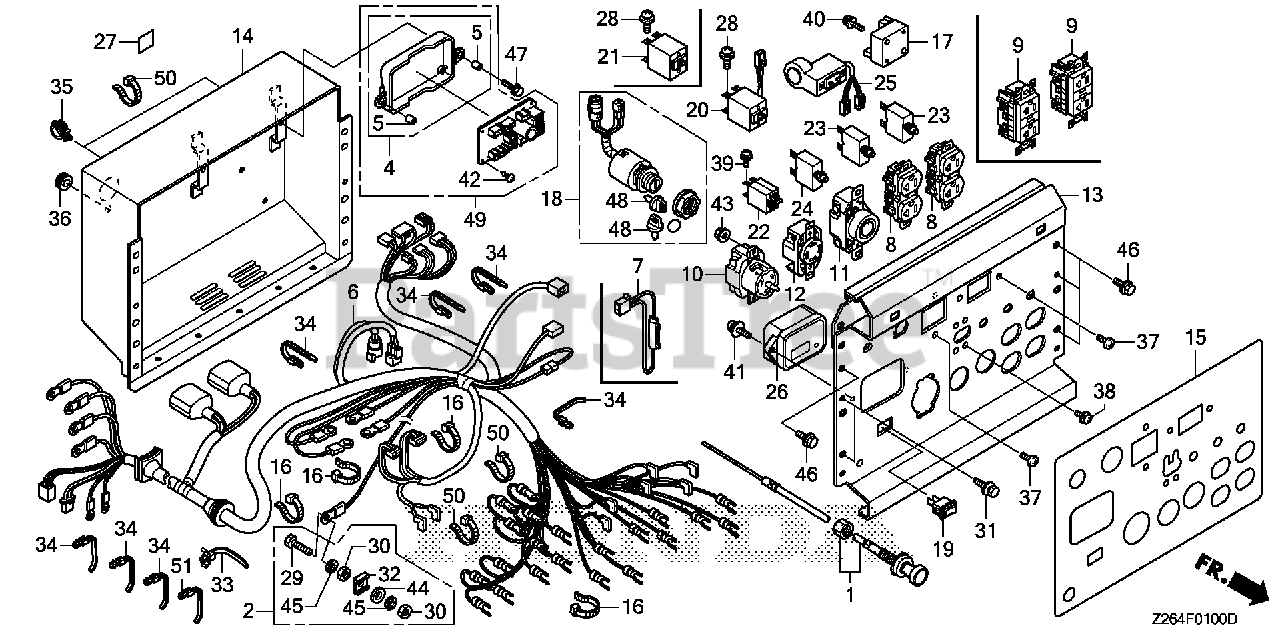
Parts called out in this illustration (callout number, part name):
1	CABLE, CHOKE
2	TERMINAL SET, GROUND
4	CASE, AUTOMATIC VOLTAGE REGULATOR
5	COLLAR, AUTOMATIC VOLTAGE REGULATOR CASE
6	WIRE HARNESS ASSY., CONTROL
9	RECEPTACLE (20A-125V) (GFCI)
10	RECEPTACLE (50A/125-250V)
11	RECEPTACLE (30A-125V)
12	RECEPTACLE (30A-125/250V)
13	PANEL, CONTROL *NH105* (MAT BLACK)
14	COVER, CONTROL BOX *NH105* (MAT BLACK)
15	MARK, PANEL (A1)
16	TIE, CABLE (C)
17	CONTROL UNIT, IDLE
18	SWITCH ASSY., COMBINATION
19	SWITCH ASSY., IDLE CONTROL
20	BREAKER, CIRCUIT (41A)
22	BREAKER, CIRCUIT (30A)
23	PROTECTOR, CIRCUIT (20A)
24	PROTECTOR, CIRCUIT (30A)
25	RELAY ASSY. (GFCI)
26	MONITOR ASSY., MULTI
27	MARK, FUSE
28	SCREW-WASHER (6X12)
29	BOLT, HEX. (6X28)
30	NUT, HEX. (6MM)
31	BOLT, GROUND (6X16) (WASHER 12.5MM) (ZN)
32	RETAINER (6MM)
33	CABLE, STRAP
34	TIE, CABLE
35	CLIP, HARNESS
36	GROMMET, CHOKE CABLE
37	SCREW, PAN (4X6)
38	SCREW-WASHER (3X6)
39	SCREW-WASHER (4X8)
40	SCREW-WASHER (5X14)
41	SCREW-WASHER (6X16)
42	SCREW, TAPPING (4X10) (PO)
43	NUT, FLANGE (4MM)
44	WASHER, PLAIN (6MM)
45	WASHER, SPRING (6MM)
46	BOLT, FLANGE (6X12)
47	BOLT, FLANGE (6X16)
48	KEY ASSY., COMBINATION SWITCH (W05)
49	CASE ASSY., AUTOMATIC VOLTAGE REGULATOR
51	TIE, CABLE
